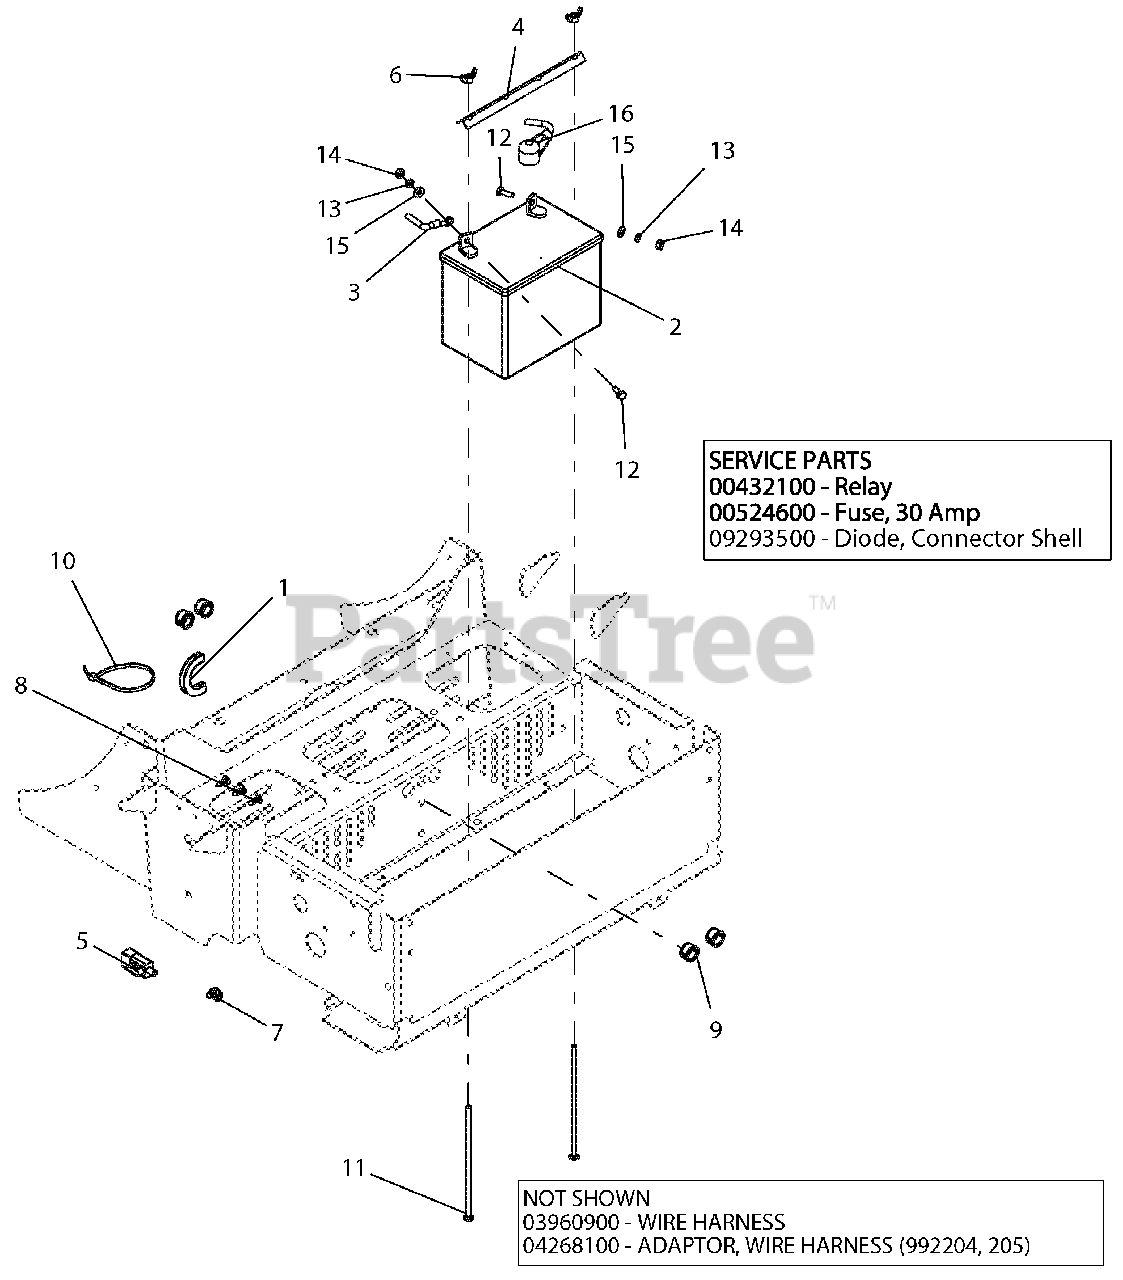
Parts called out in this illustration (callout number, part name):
1	STRIP, COWL - 1.50 LG
2	BATTERY, 300 CCA 10U1L
3	CABLE, NEGATIVE BATTERY 35.00"
4	HOLD DOWN - BLK
5	SWITCH, SNAP IN -N.O./N.O
6	NUT-LOCKING WING 1/4-20
7	CABLE TIE W/ TREE (.25 HOLE)
8	RIVET, .25 NYLON PANEL
9	BUSH, PANEL SNAP .687X.875X.56
10	CABLE, TIE 5.50 LG
11	BLT-RDHDSQNK .25-20X7.50 G2 YWZC
12	BLT-HEX .25-20X.75 GR5 YWZC
13	WSHR-LK .25X.062 REG YWZC
14	NUT-HEX .25-20 YWZC
15	WSHR-FL-STL.281X.62X.065 YWZC
16	CABLE, POS BATT W/ BOOTS 6 X 35
